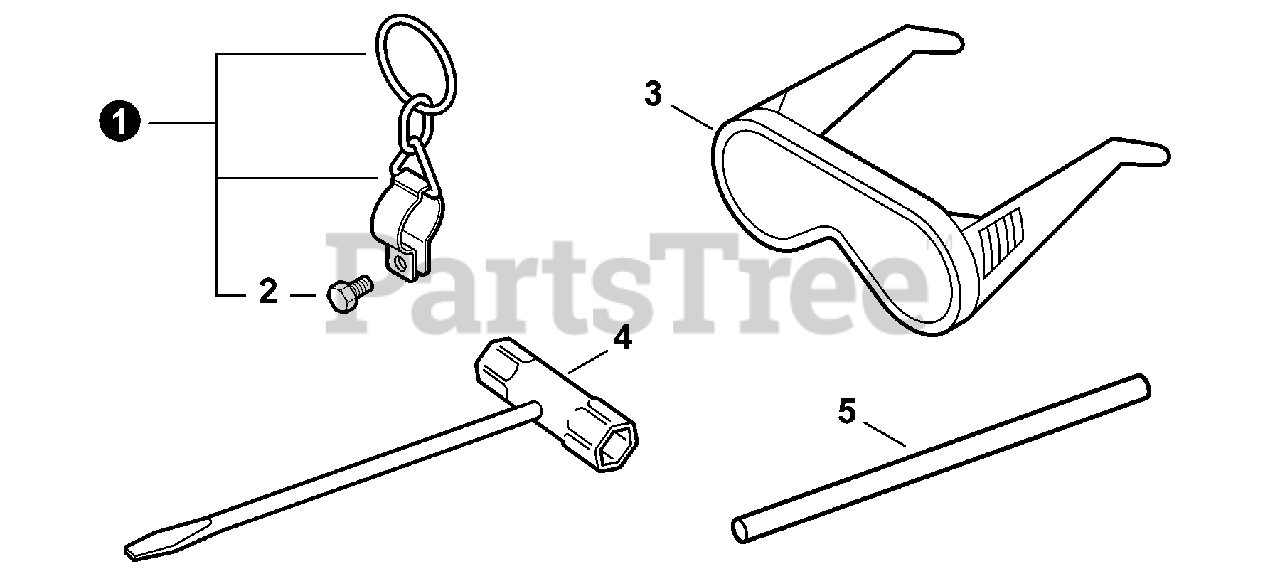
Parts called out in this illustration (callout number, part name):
1	HANGER SET, HARNESS
2	BOLT 5×12
3	GLASSES, SAFETY
4	T-WRENCH 17x-19 L200
5	TOOL, LOCKING 5×120 MM
